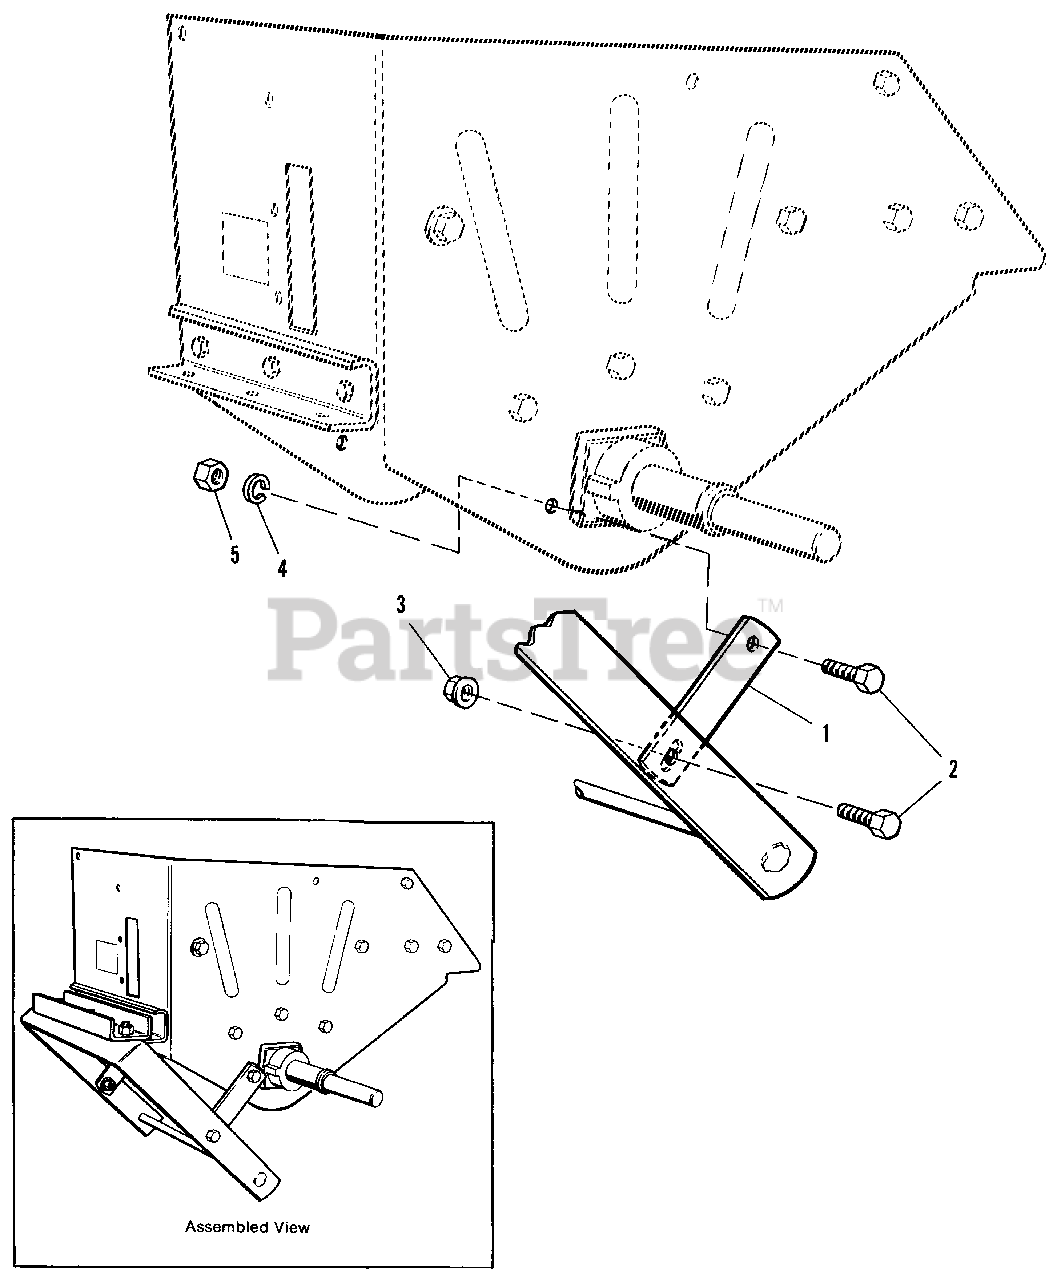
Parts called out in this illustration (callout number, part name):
1	BRACE, Hitch
2	CAPSCREW, Hex Hd., 3/8-16 x 1
3	LOCKNUT, Flange, 3/8-16
4	LOCKWASHER, 3/8
5	NUT, Hex, 3/8-16
